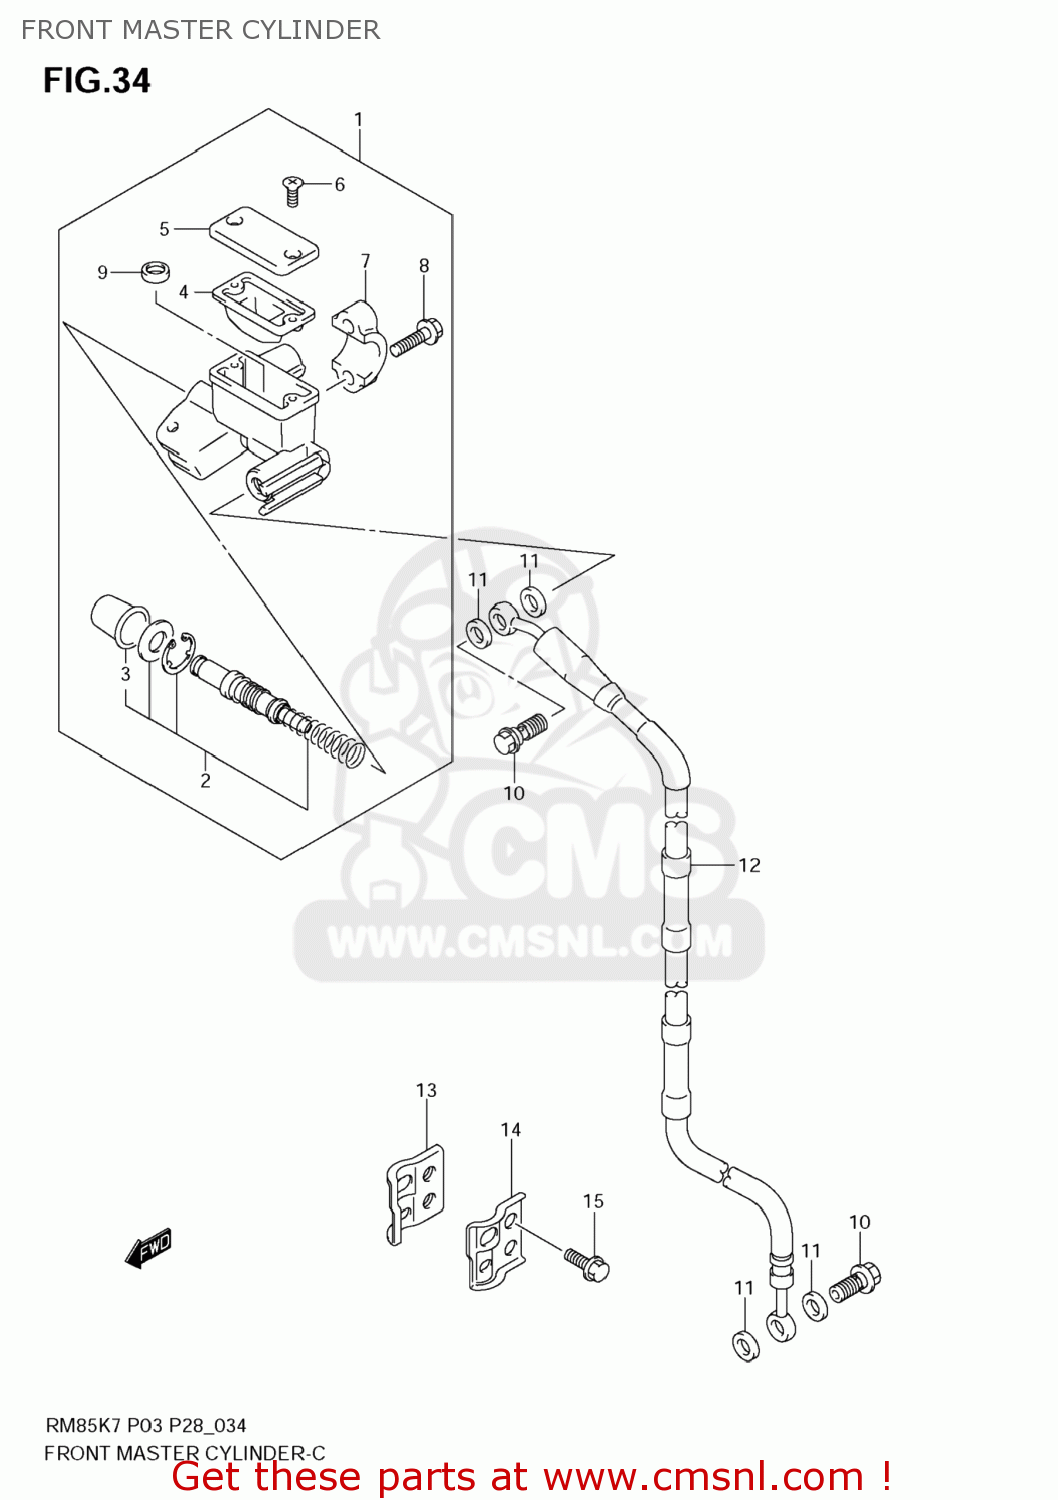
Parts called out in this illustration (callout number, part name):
1	CYLINDER ASSY,FR MASTER
2	PISTON & CUP SET
3	BOOT
4	DIAPHRAGM
5	CAP
6	SCREW
7	HOLDER
8	BOLT
9	SEPARATOR
10	BOLT UNION
11	WASHER(10X15X1.5)
12	HOSE,FR BRAKE
13	CLAMP,FR BRAKE HOSE INNER
14	CLAMP,FR BRAKE OUTER
15	BOLT(6X16)
